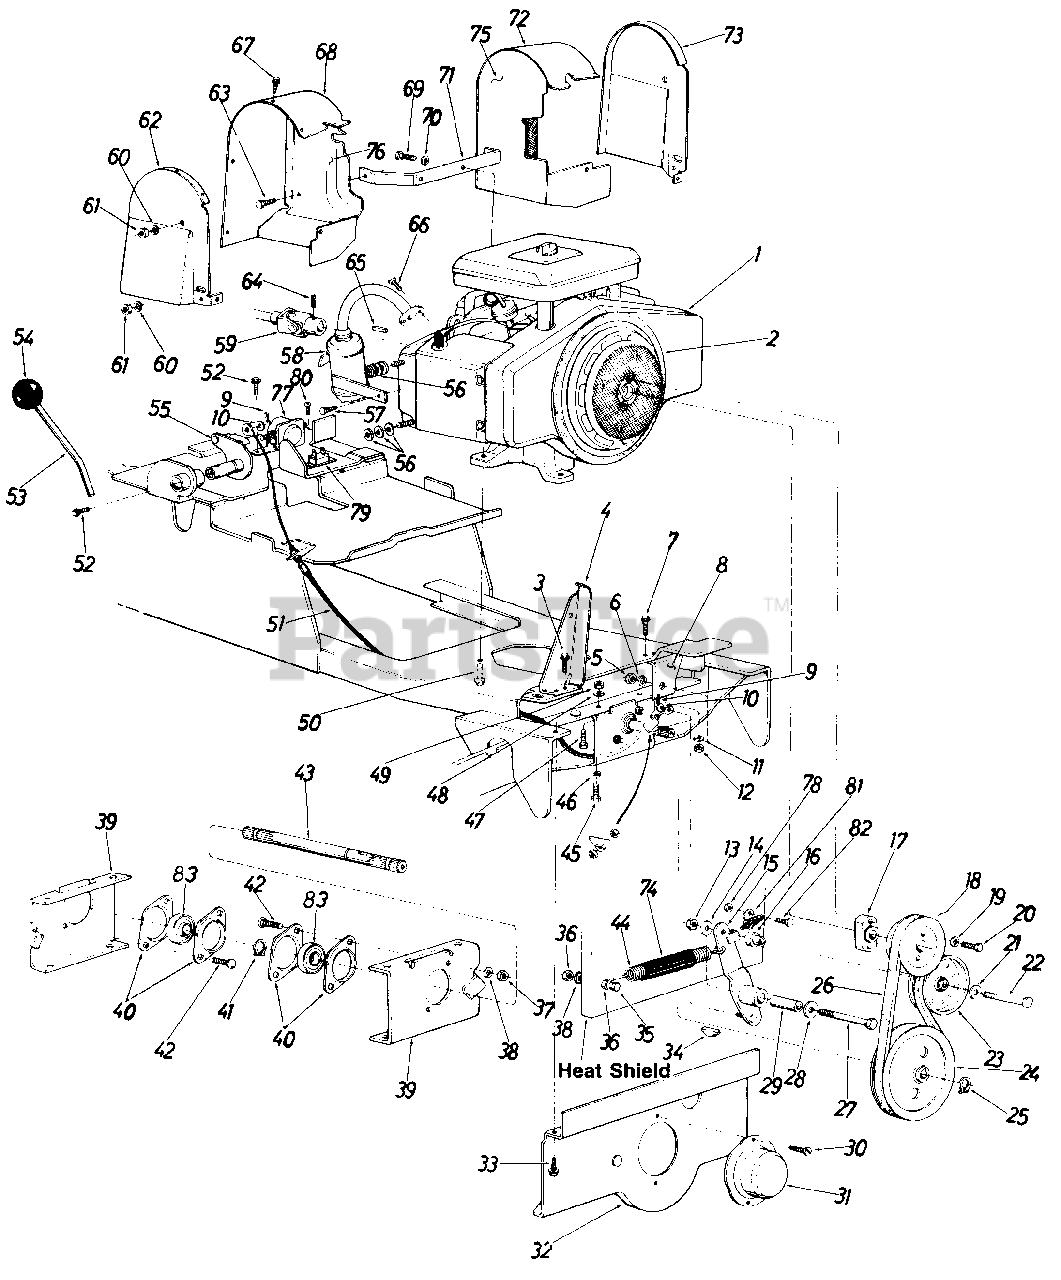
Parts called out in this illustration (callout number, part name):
1	Engine
2	Mylar Foam Strip
3	Hex Wash. Hd. Self-Tap Scr. 1/4-20 x .75" Lg.
6	L-Wash. 3/8" Scr.*
7	Hex Wash. Hd. Self-Tap Scr. 5/16-18 x .75" Lg.
10	Fl-Wash 38" I.D. x 1.25 O.D. x .10 Thk.
11	L-Wash. 3/8" Scr.*
12	Hex Nut 3/8-16 Thd.*
13	Hex Nut 3/8-16 Thd.*
14	Fl-Wash. .38 I.D. x 1.25" O.D. x .10 Thk.
17	Pulley Spacer
18	1/2" V-Pulley 4.75" O.D.
19	L-Wash. 3/8" Scr. H.D.
20	Hex Scr. 3/8-16 x 2.00" Lg*
21	Fl-Wash. .38" I.D. x 1.25 O.D. x .010 Thk.
22	Hex Scr. 3/8-16 x 2.50" Lg.*
23	Flat Idler Pulley
24	1/2" V-Pulley 7.00" O.D.
25	Snap Ring
26	"V"-Belt 1/2 " x 41 " Lg .
27	Hex Scr. 3/8-16 x 2.50" Lg.*
28	Fl-Wash. .38" I.D. x 1.25" O.D. x .010
29	Spacer .375" I.D. x .62" O.D. x 1.830 Lg.
30	Hex "B" Tap Scr. #10 x .50" Lg.
34	#91 Hi-Pro Key
35	Hex Scr. 5/16-18 x 1.25" Lg.
36	Hex Nut 5/16-18 Thd.*
37	Hex Nut 5/16-18 Thd.*
38	L-Wash. 5/16" Scr.*
39	PTO Brg. Retainer Brkt.
40	1.00" Dia. Brg. w/Flangette
41	Snap Ring
42	Carr. Bolt 5/16-18 x .75" Lg.*
43	Spline Shaft
44	Extension Spring
45	Hex Scr. 3/8-16 x 1.00" Lg.
46	L-Wash. 3/8" Scr.t
47	Hex Scr. 3/8-16 x 1.00" Lg.
48	L-Wash. 3/8" Scr.
49	Hex Nut 3/8-16 Thd.
50	Hex Wash. Hd. Self-Tap Scr. 3/8-16 x 1.25" Lg.
51	PTO Control Cable
52	Hex Wash. Hd. Self-Tap Scr. 1/4-20 x .50"
53	PTO Handle
54	Ball Knob
55	PTO Actuator Lever Ass'y.
56	Fl-Wash. .312" I.D. x 1.620" O.D. x .060
57	Hex Wash. Hd. Self-Tap Scr. 1/4-20 x .50" Lg.
58	Muffler Ass'y. Comp.-R.H.
59	Universal Joint Ass'y. Comp.
60	Fl-Wash. .312" I.D. x .630" O.D. x .063
61	Hex Nut 5/16-18 Thd.
62	Shroud Outer-R.H.
63	Hex Wash. Hd. Self-Tap Scr. 1/4-20 x .50" Lg.
64	Sq. Hd. Set Scr. 5/16-18 x .38" Lg.
65	Sq. Key 1/4" x 2.00" Lg.
66	Hex Wash. Hd. Scr. 1/4-20 x 518" Lg.-Grade 5
67	Hex "AB" Tap Scr. #10 x .50" Lg.
68	Shroud Cover-R.H.
69	Hex Scr. 5/16-24 x .75" Lg.
70	L-Wash. 5116" Scr.
71	Shroud Support Brkt.
72	Shroud Cover-L.H.
73	Shroud Outer-L.H.
74	Spring Cover Tubing
75	Shroud Inner Ass'y.-L.H.
76	Shroud Inner Ass'y.-R.H.
77	Solenoid
78	Hex Scr. 1/4-20 x 1/2" Lg.
79	Circuit Breaker
80	Truss Mach. Scr. #10 x .50" Lg.
81	Safety Switch
82	L-Wash. 1/4" Scr.
83	Ball Bearing
